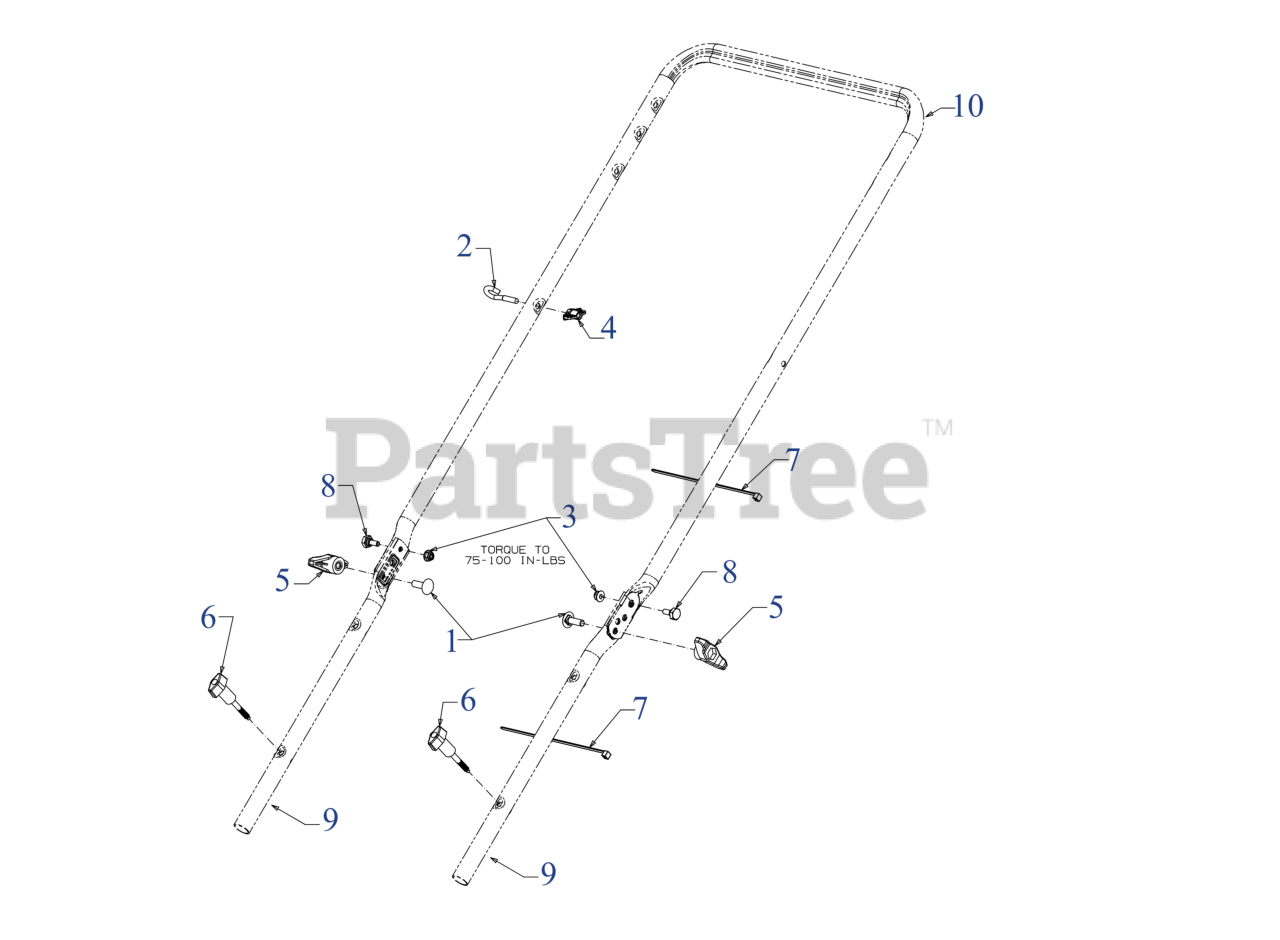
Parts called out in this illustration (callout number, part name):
1	SCREW 5/16-18 x 1.00 GR5
2	EYEBOLT 1/4-20
3	FLANGE LOCK NUT
4	HANDLE KNOB
5	WING KNOB 5/16-18
6	WING KNOB 1/4-20
7	7" CABLE TIE
8	SHOULDER SCREW
9	LOWER HANDLE
10	UPPER HANDLE
